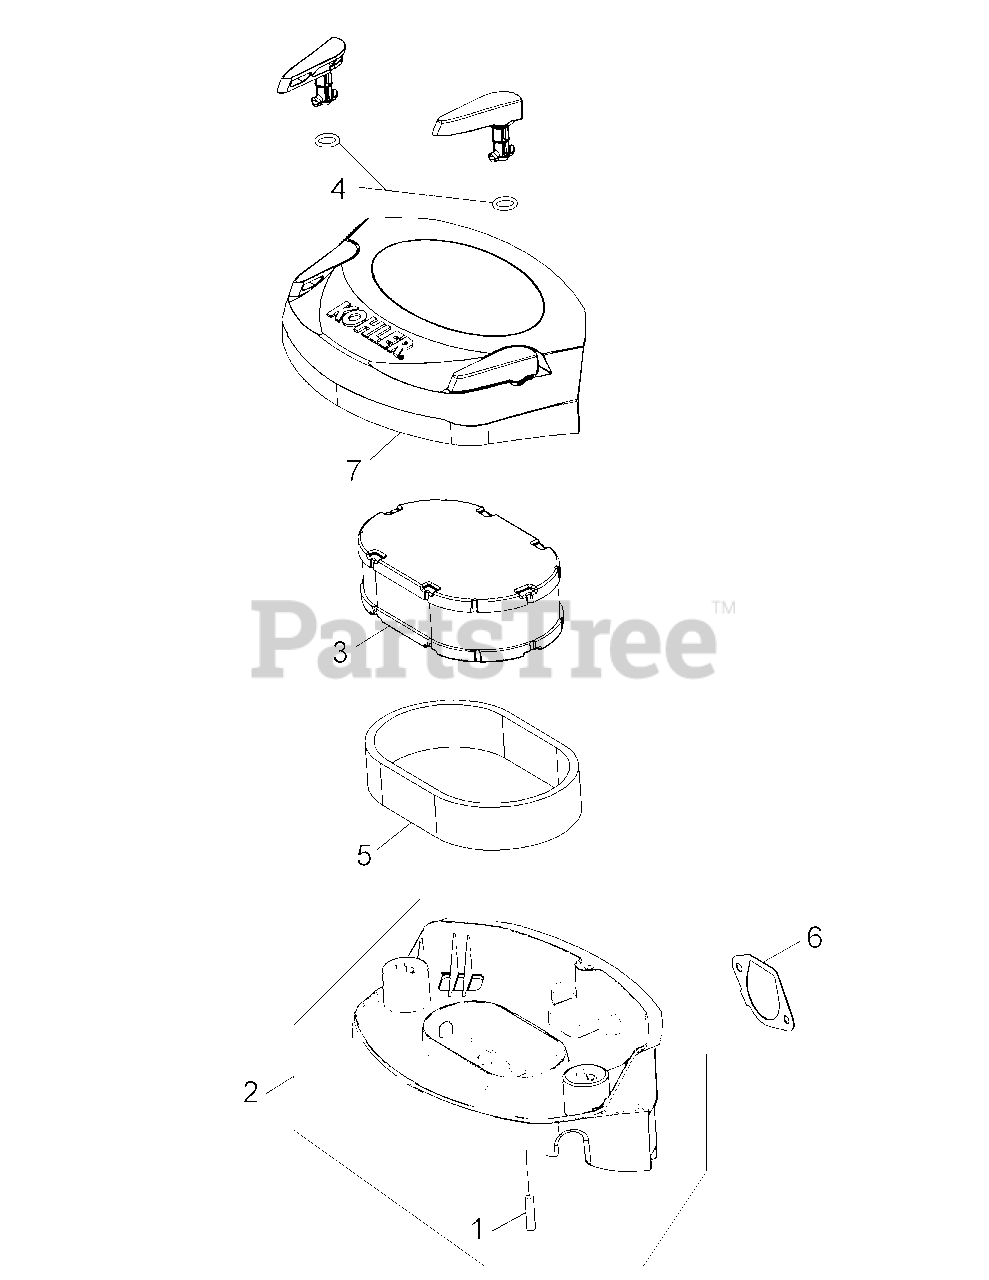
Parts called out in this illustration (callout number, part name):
2	Air Cleaner Base Assembly
3	Air Filter Element
5	Pre-Cleaner Element
6	Air Cleaner Base Gasket
7	Air Cleaner Cover Assembly
